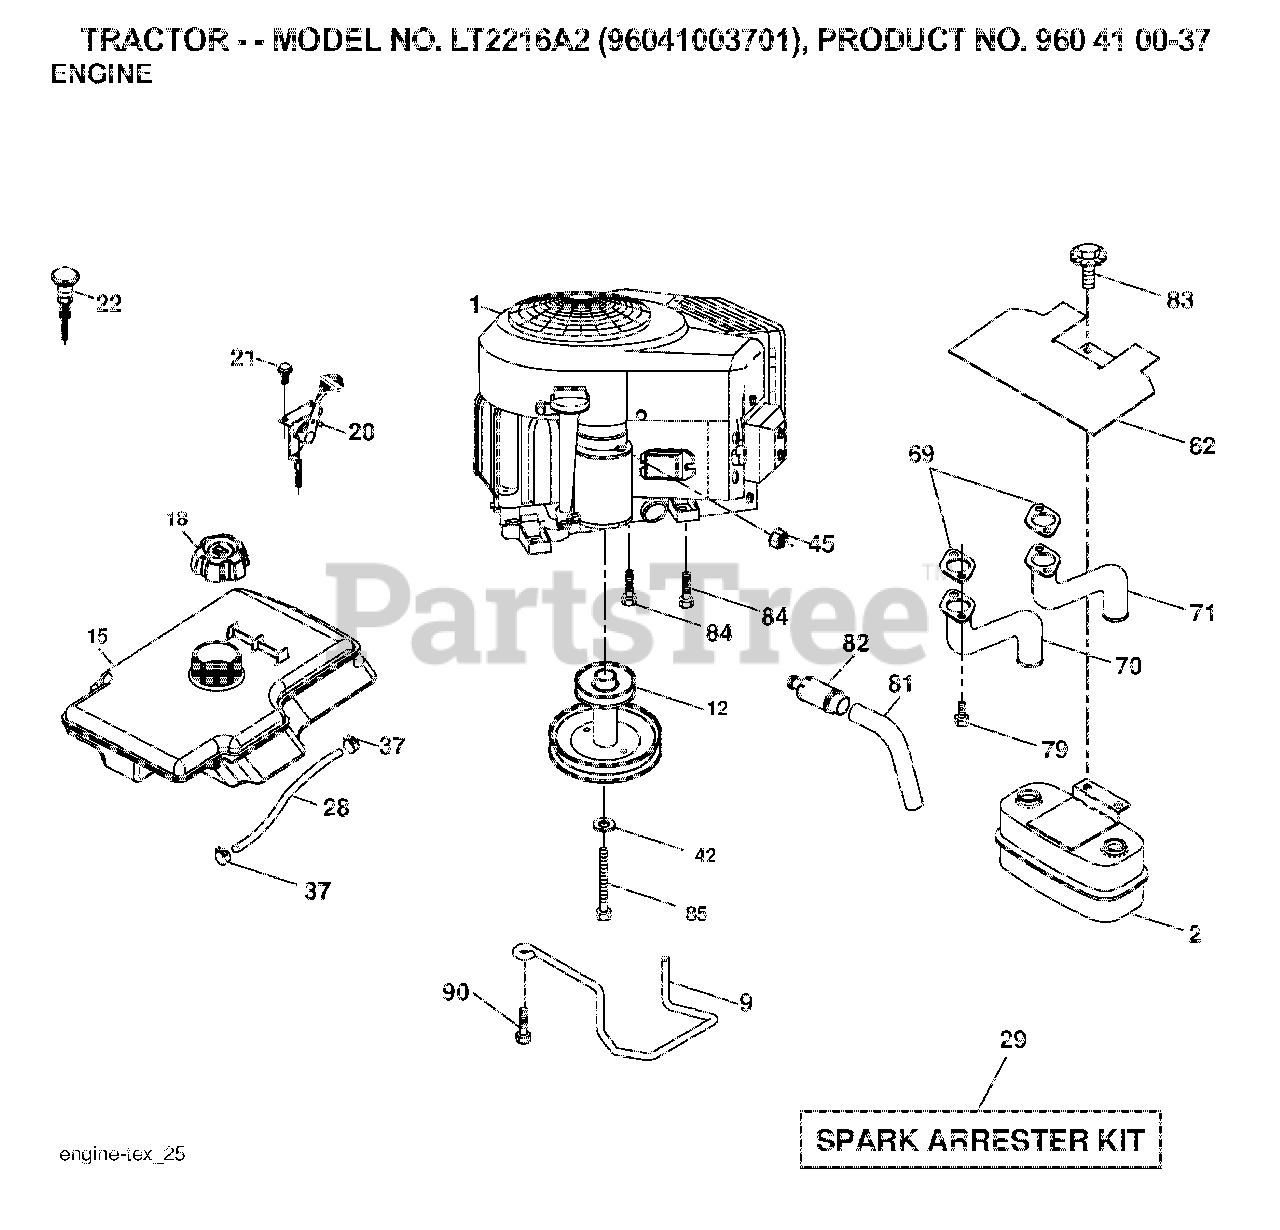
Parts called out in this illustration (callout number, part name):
9	KEEPER.BELT.ENGINE.3.25
12	PULLEY ENGINE
18	CAP.ASM.FUEL.TANK.3"BL
20	THROTTLE CABLE
21	SCREW
22	CONTROL CHOKE
29	ARRESTER SPARK (OPTIONAL)
37	HOSE CLAMP
42	LOCKWASHER
45	NUT
62	RP SHIELD HEAT MUFFLER
69	GASKET.MUFFLER
70	TUBE MANIFOLD LH
71	EXHAUST TUBE RH
79	SCREW.SOCKET.HEAD.5/16-18
81	TUBE, DRAIN OIL ASM.
82	PLUG DRAIN OIL EASY
83	BOLT, 5/16-18 X 1 3/4
84	SCREW.3/8-16
85	BOLT HEX 7/16-20X4-1/4"
90	SCREW 3/8-16X1
